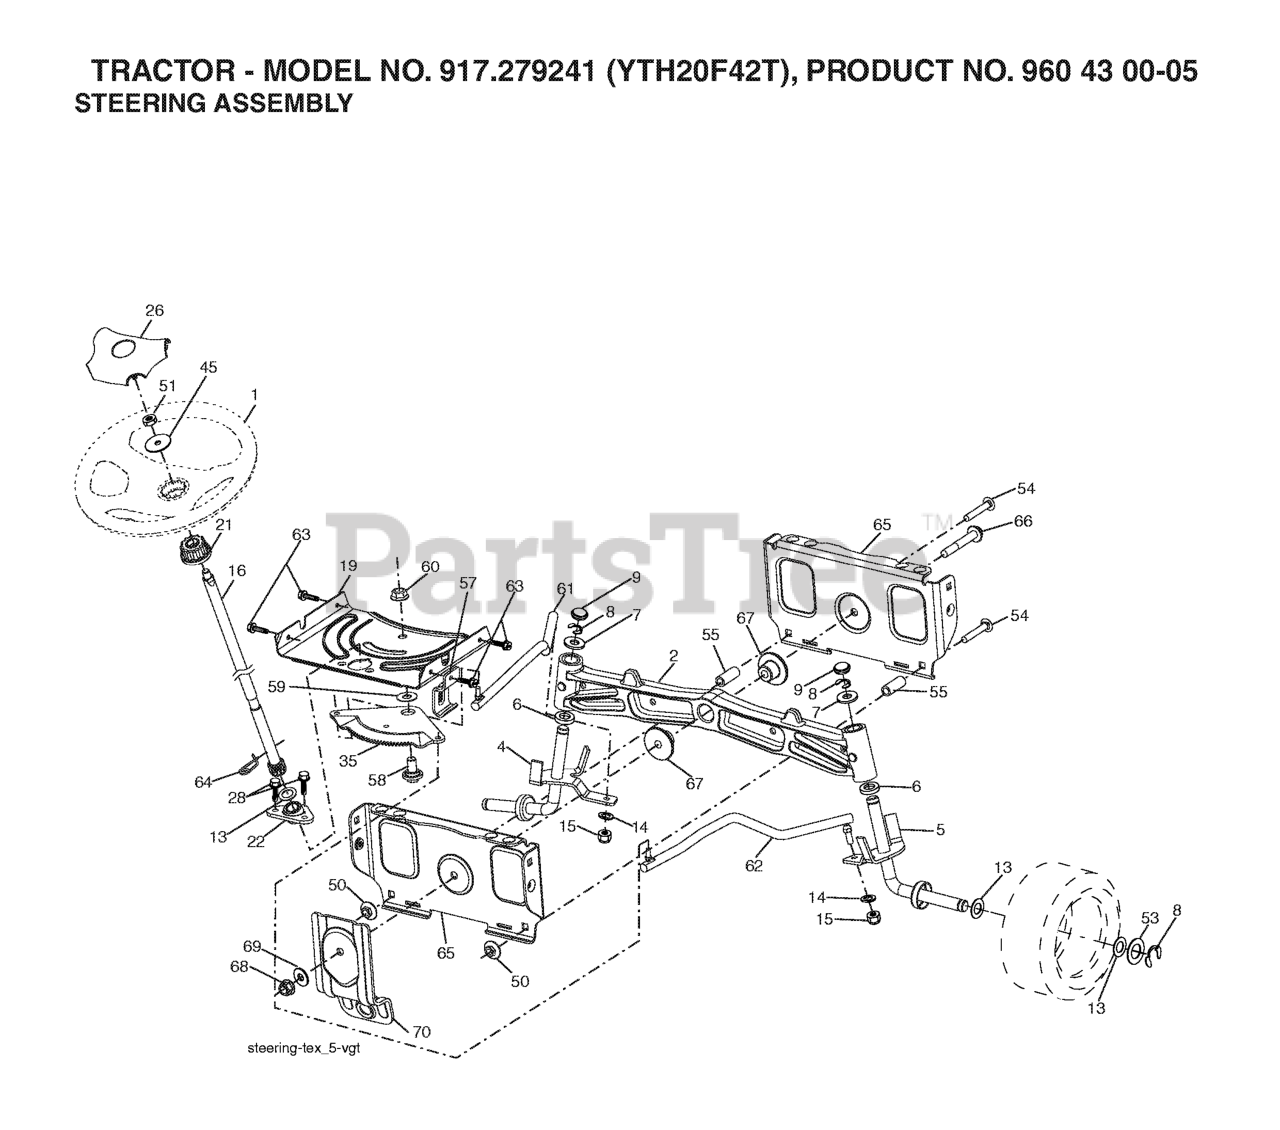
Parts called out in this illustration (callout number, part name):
1	WHEEL.STEERING.LEGEND2.GRY
2	AXLE.CAST.IRON
4	SPINDLE.WELDED.LH.15"TEX
5	SPINDLE.WELDED.RH.15"T
6	THRUST WASHER
9	CAP.SPINDLE.BLACK
14	WASHER, LOCK 3/8
15	NUT CROWNLOCK 3/8-24
16	SHAFT.STEER.STEALTH.DD
19	PLATE.STEER.DDL.NLT/NG
21	ADAPTER, WHEEL STNG..
22	BUSHING.ASM.STEERING.A
26	INSERT.CAP.STRG.WH.GRAY
28	SCREW, 3/8-16X3/4
35	GEAR.SECTOR.PLATE.DDL.
45	WASHER 9/16"ID, 2 3/8"OD
50	NUT LOCK FLG 3/8-16 UNC
51	NUT.HEX.1/2-20
53	WASHER.HARDENED
55	SPACER.BRACE.AXLE (2 2)
57	BRKT.UPSTOP.GT/LT.TEX
58	BOLT.SHOULDER.SECTOR.P
59	WASHER.THURST.SECTOR.S
60	NUT FLANGE LOCK 5/8-11
61	DRAGLINK.LH.BALLSTUD.D
62	DRAGLINK.RH.BALLSTUD.D
63	SCREW
64	RETAINER.CLIP.SPRING.S
65	BRACE.AXLE.FRONT.NLT/N
66	BOLT HEX FGHD 7/16-14 X 3 SERR
67	BUSHING.PM.FRONT AXLE
68	NUT.LOCK.FLANGE.7/16
69	WASHER.1.5X.505X.118
70	BRKT.DECK.SUSPENSION.F
